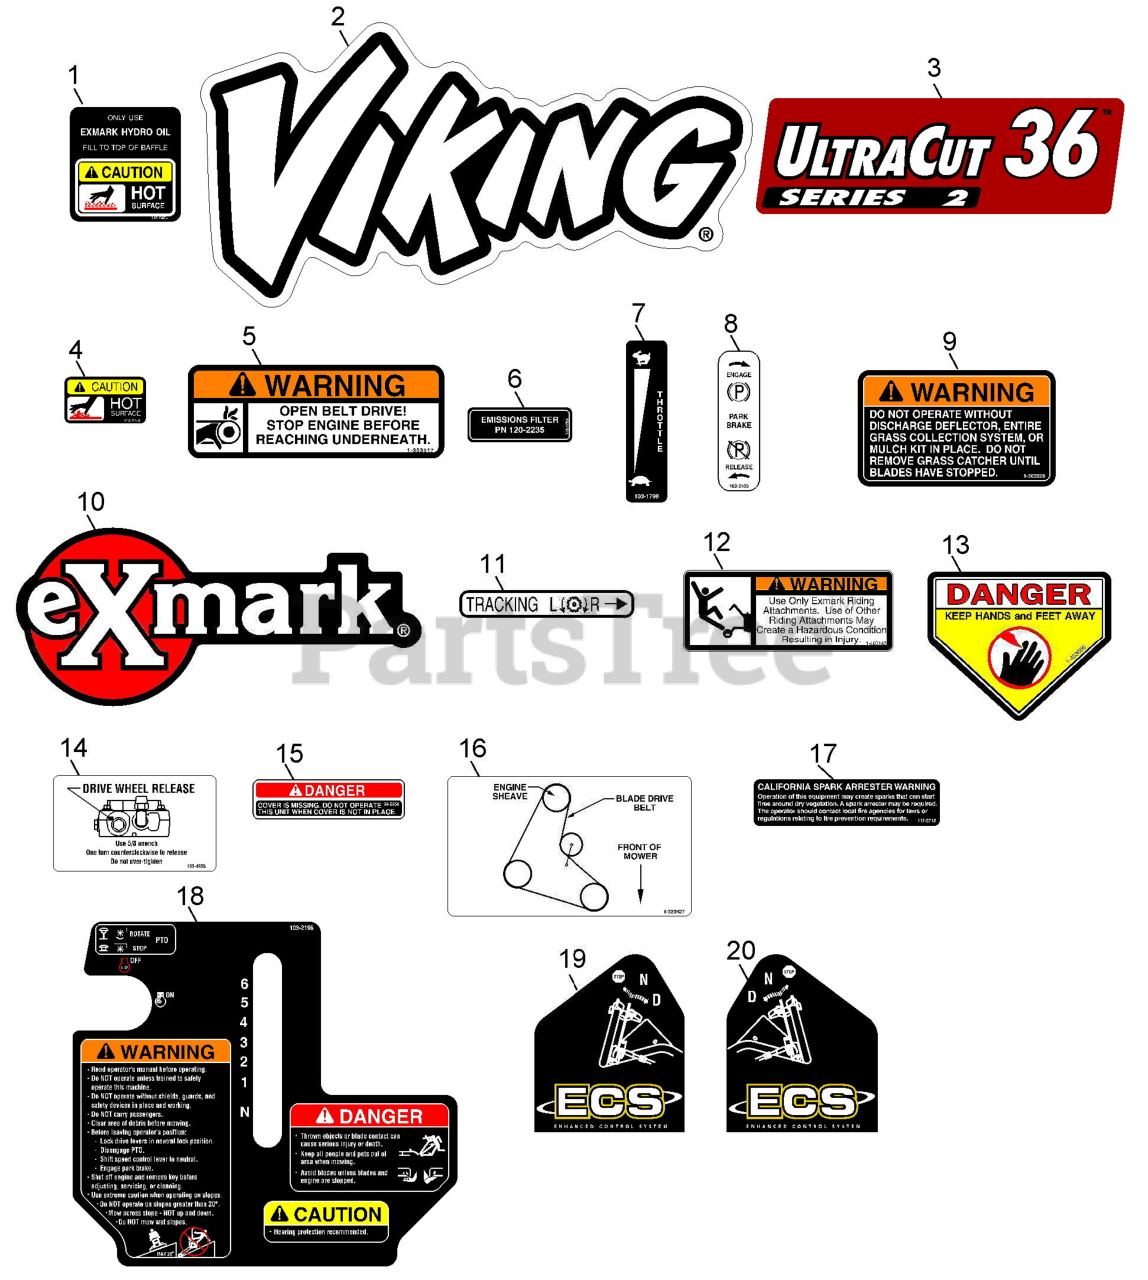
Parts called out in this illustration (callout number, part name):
1	DECAL-HYDRAULIC TANK
2	DECAL,VH MODEL
3	DECAL-ULTRACUT 36 SERIES
4	DECAL-CAUTION
5	DECAL,BELT DRIVE
6	DECAL-FILTER, EMISSIONS
7	DECAL,THROTTLE ONLY
8	DECAL-BRAKE, PARK
9	DECAL-WARNING, DISCHARGE
10	DECAL,EXMARK LOGO
11	DECAL,TRACKING ADJUST
12	DECAL,SULKY WARNING
13	DECAL-DANGER
14	DECAL,DRIVE RELEASE
15	DECAL-COVER, MISSING
16	DECAL,BELT ROUTING 32/36
17	DECAL-ARRESTER, SPARK
18	DECAL,CONSOLE VH ECS
19	DECAL,LH ECS INSTRUCTION
20	DECAL,RH ECS INSTRUCTION
